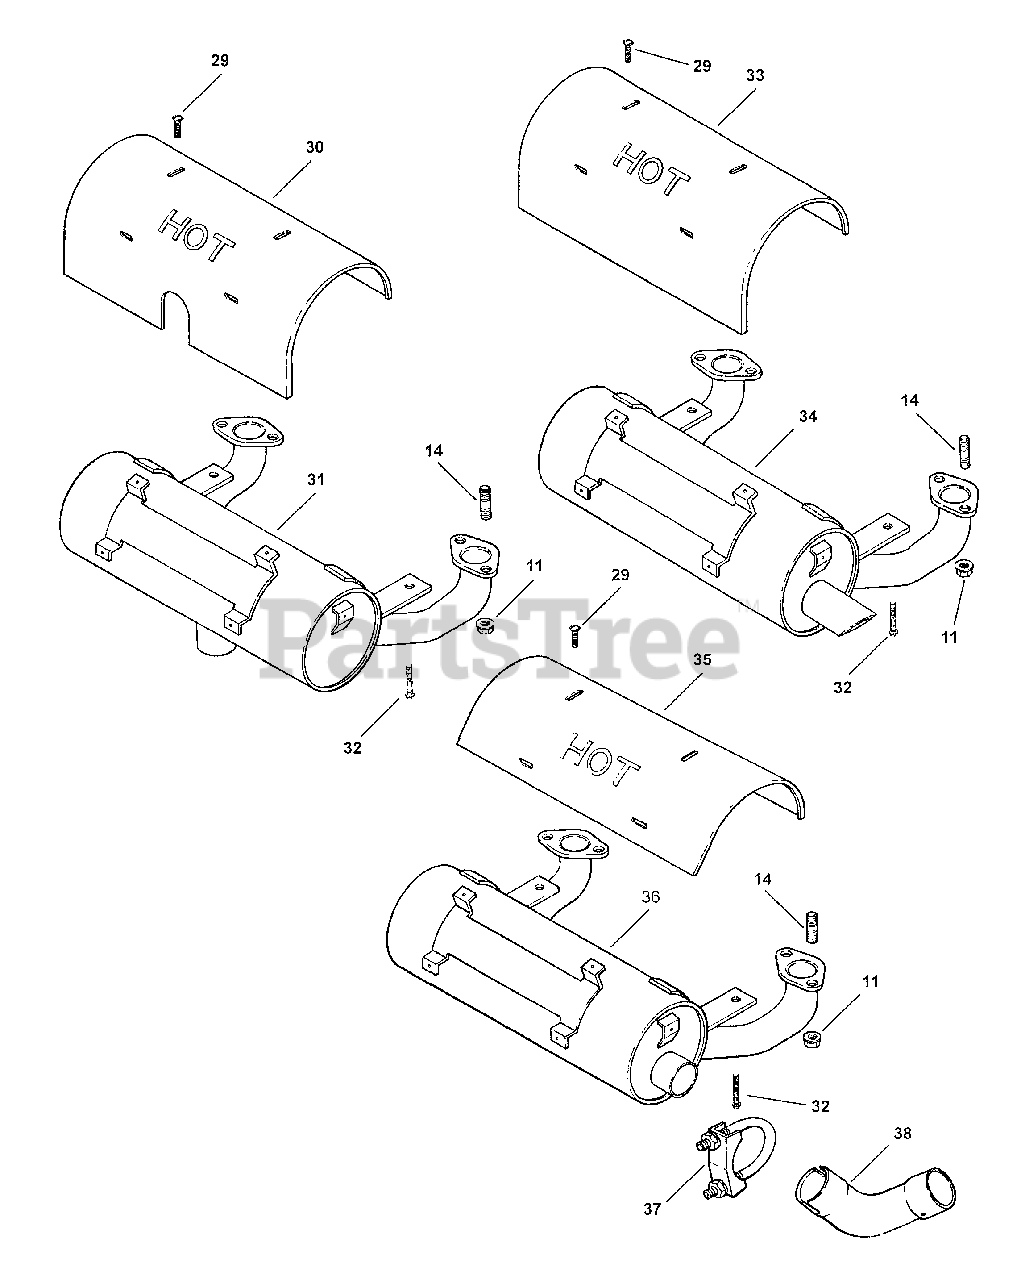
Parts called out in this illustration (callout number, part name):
11	NUT - USE M-841080
14	STUD - USE M-829033
29	SCREW, SEMS DRILL #8-18X1/2"
32	SCREW - USE M-645020
33	DUCT, HEAT SHIELD
